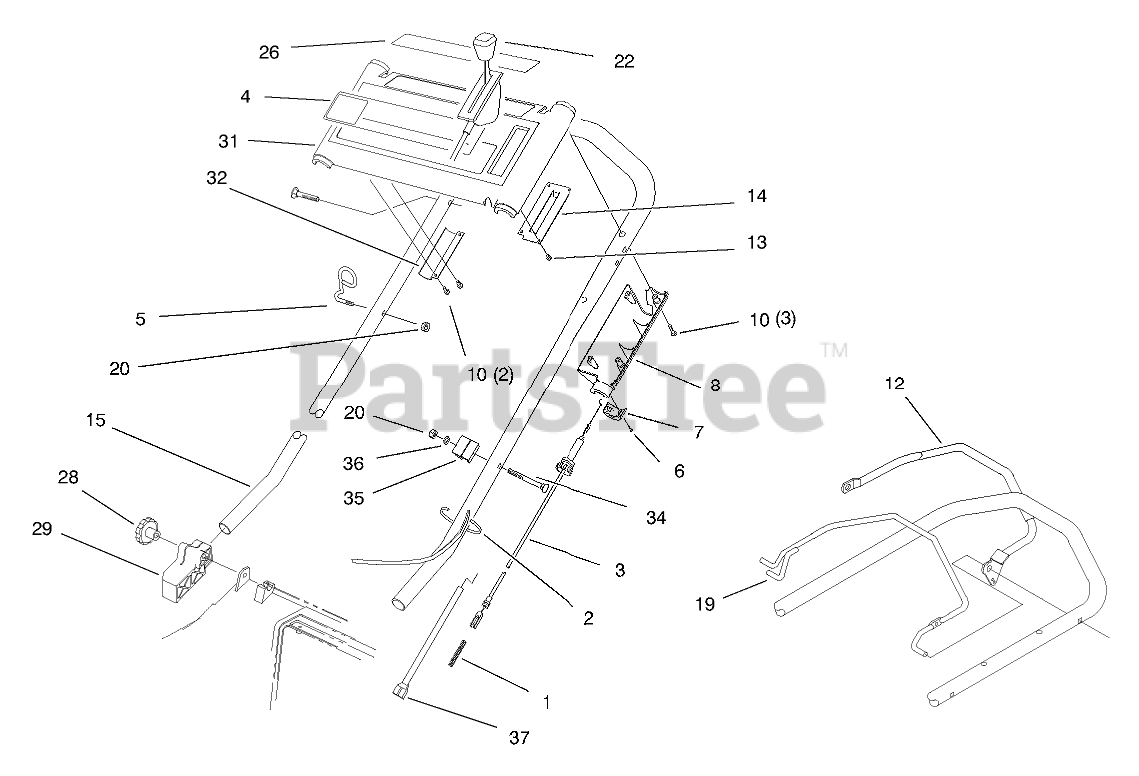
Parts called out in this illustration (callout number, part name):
1	SPRING-COMPRESSION
2	TIE-CABLE
3	CABLE - TRACTION
4	DECAL - PANEL
5	GUIDE-ROPE
6	#4-14X.62 PLASTITE SCW
7	LOWER THROTTLE CAP
8	COVER-THROTTLE, LEVER
10	SCREW-PPH, PLASTITE
12	Bail-Traction
13	#6-19X.25 PLASK FORM SC
14	THROTTLE PLATE
15	Handle
19	Bail-Brake
20	NUT-LOCK, NI
22	CONTROL - THROTTLE
26	DECAL - CONTROL PANEL
29	MOUNT-HANDLE, RH
31	Panel-Control (Incl. Ref. #4, 26)
32	Bracket-Panel
34	SCREW
35	ANCHOR-CABLE, UPPER
36	WASHER-FLAT
37	CABLE - BRAKE
